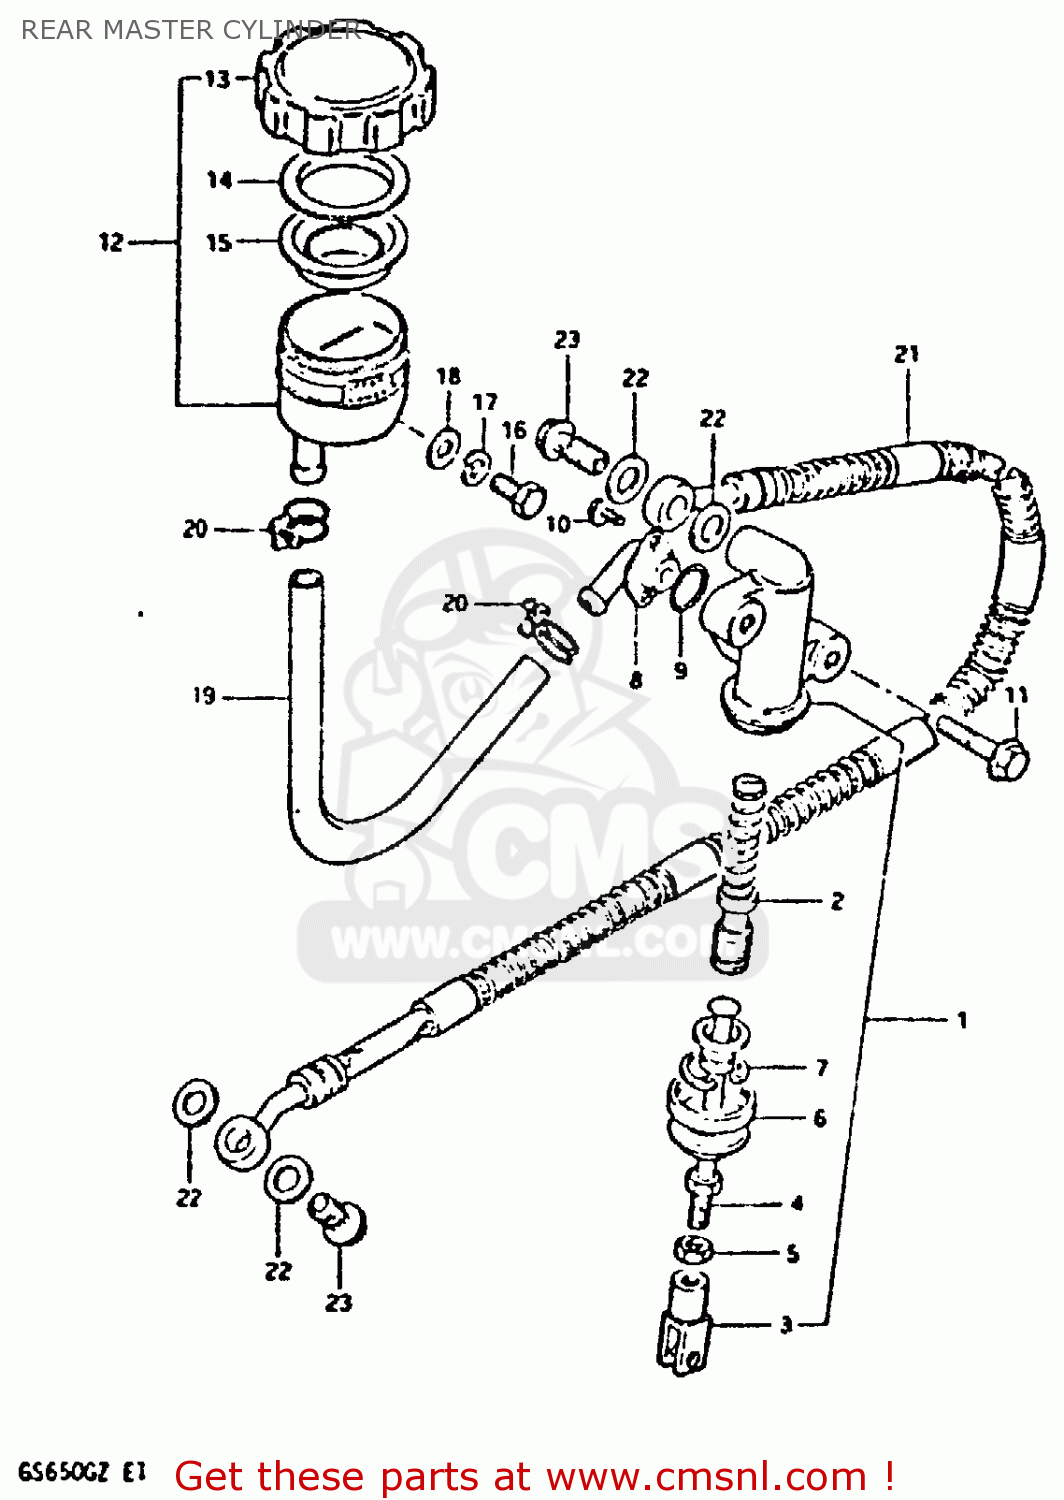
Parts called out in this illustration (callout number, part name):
1	CYLINDER ASSEMBLY,REAR MASTER
2	PISTON/CUP SET
3	YOKE
4	ROD,REAR MASTER CYLINDER
5	NUT
6	BOOT
7	CIRCLIP
8	CONNECTOR
9	O RING
10	SCREW
11	BOLT
12	TANK ASSEMBLY,RESERVOIR
13	CAP
14	PLATE,DIAPHRAGM
15	DIAPHRAGM
16	BOLT, UPPER
17	LOCK WASHER
18	WASHER
19	HOSE,RESERVOIR TANK
20	CLAMP
21	HOSE,REAR BRAKE
22	WASHER
23	BOLT,UNION
